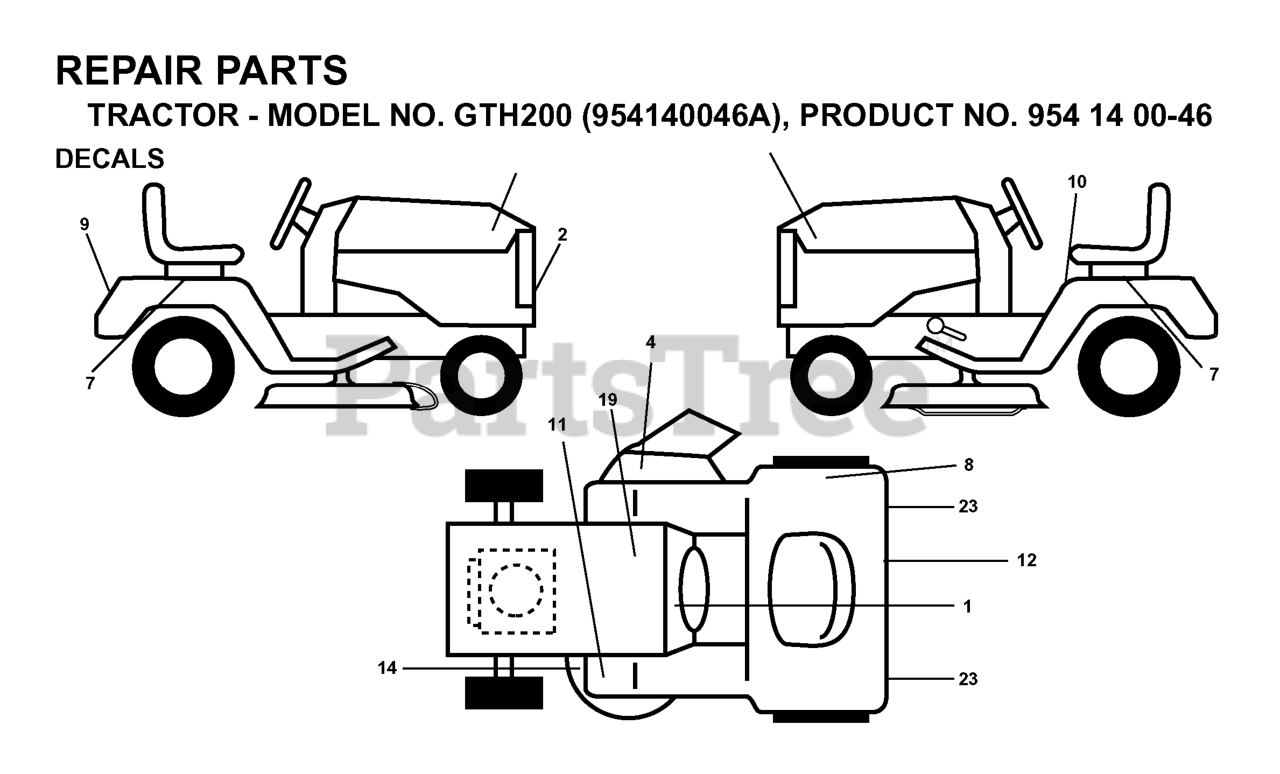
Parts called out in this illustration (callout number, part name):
2	DECAL.GRILLE.HUSQ
4	DECAL WARNING (ENGLISH/FRENCH)
6	HOOD DECAL
7	DECAL, FENDER
9	DECAL FENDER HUSQ
10	DECAL FENDER DANGER
12	DECAL PARK BRAKE
14	DECAL V-BELT SCHEMATIC
19	DECAL BTRY SYMBOLS
23	REFLECTOR-TAIL YT
